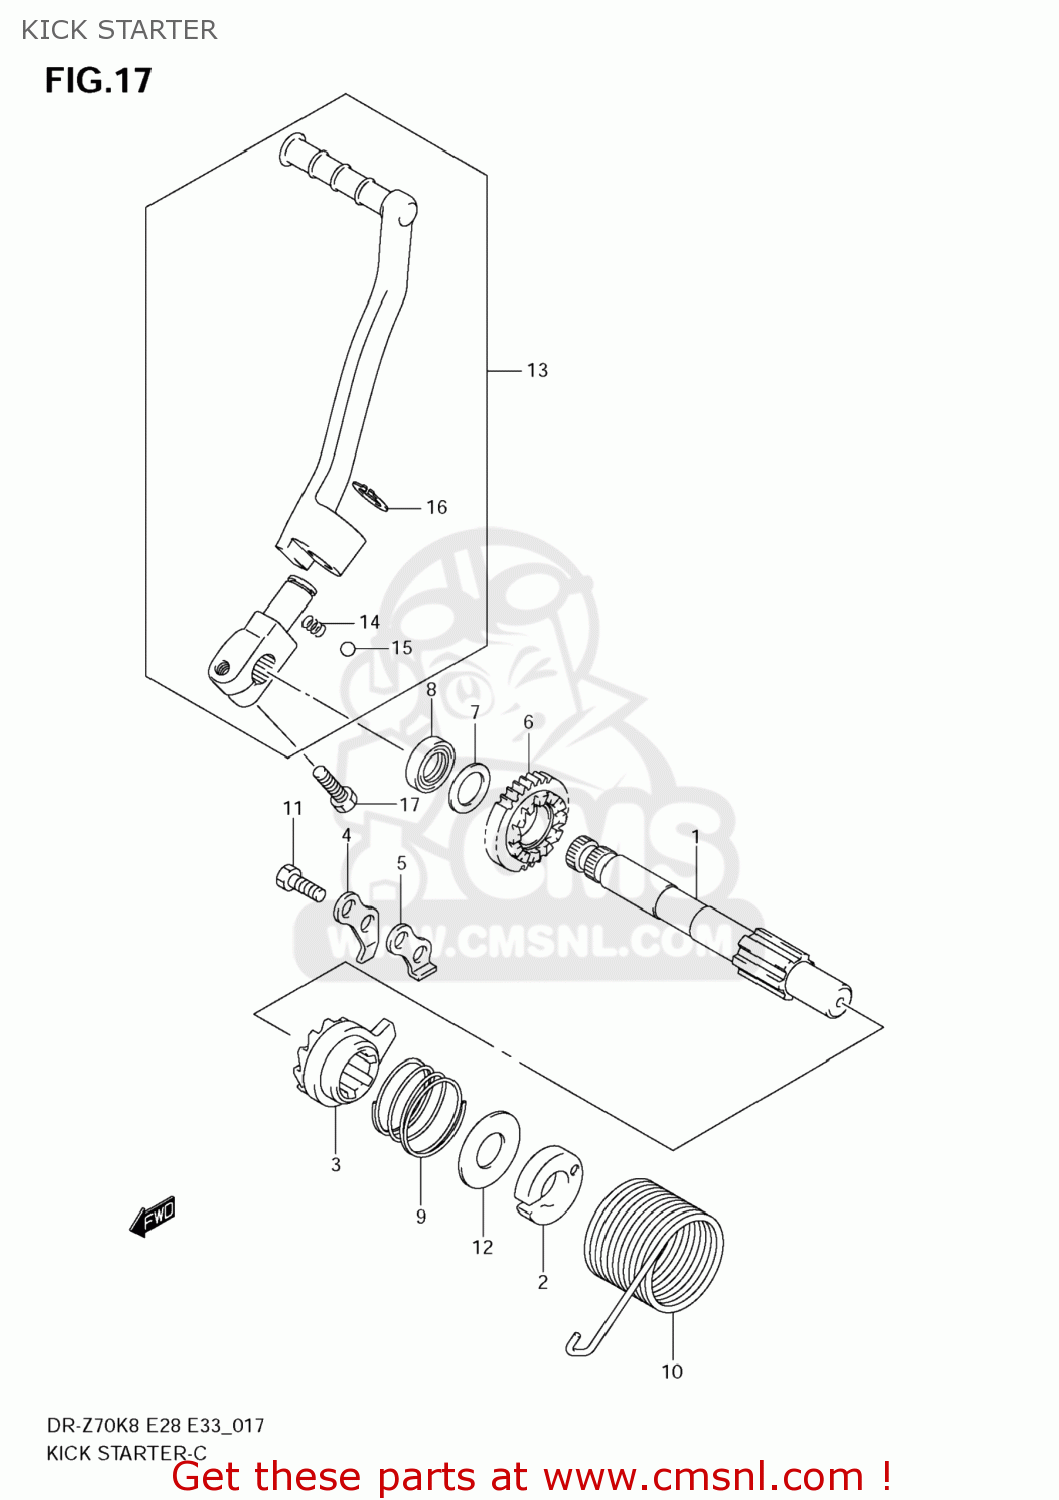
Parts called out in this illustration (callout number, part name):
1	SHAFT,KICK STARTER
2	GUIDE,KICK STARTER SPRING
3	STARTER,KICK
4	GUIDE,KICK STARTER
5	STOPPER,KICK STARTER
6	GEAR,KICK STARTER DRIVE(NT:20)
7	SHIM(14X22X1)
8	SEAL,OIL(14X24X6)
9	SPRING
10	SPRING
11	BOLT
12	WASHER
13	LEVER ASSY,KICK STARTER
14	SPRING
15	BALL
16	CIRCLIP
17	BOLT
